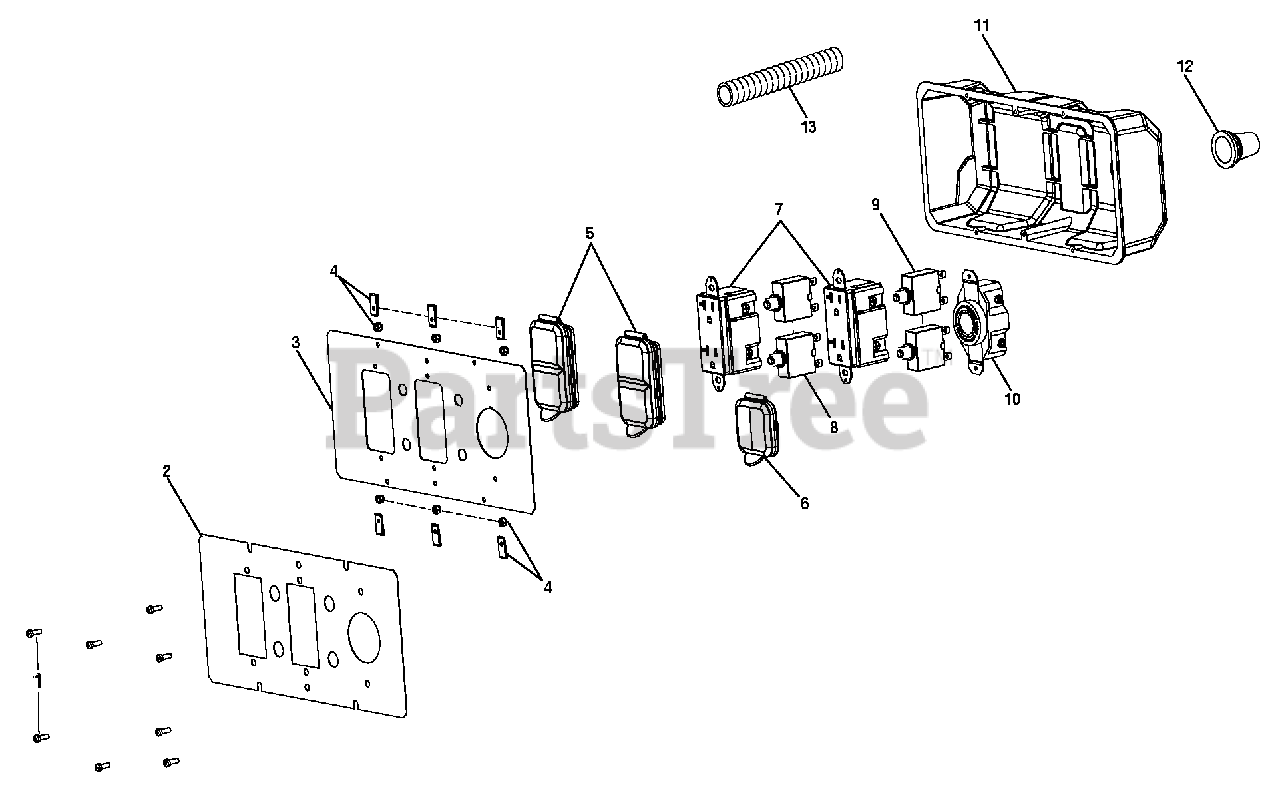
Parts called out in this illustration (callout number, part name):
1	Screw (6-20 x 3/8 in.)
2	Label (Power Outlet)
3	Front Panel
4	U-Clip Nut
5	Outlet Cover (120 Volt)
6	Outlet Cover (240 Volt)
7	Duplex Receptacle (120 Volt)
8	Circuit Breaker, 20 Amp
9	Circuit Breaker, 30 Amp
10	Twist Lock Receptacle (240 Volt)
11	Control Box (Back Panel)
12	Rubber Boot
13	Wire Sleeving
